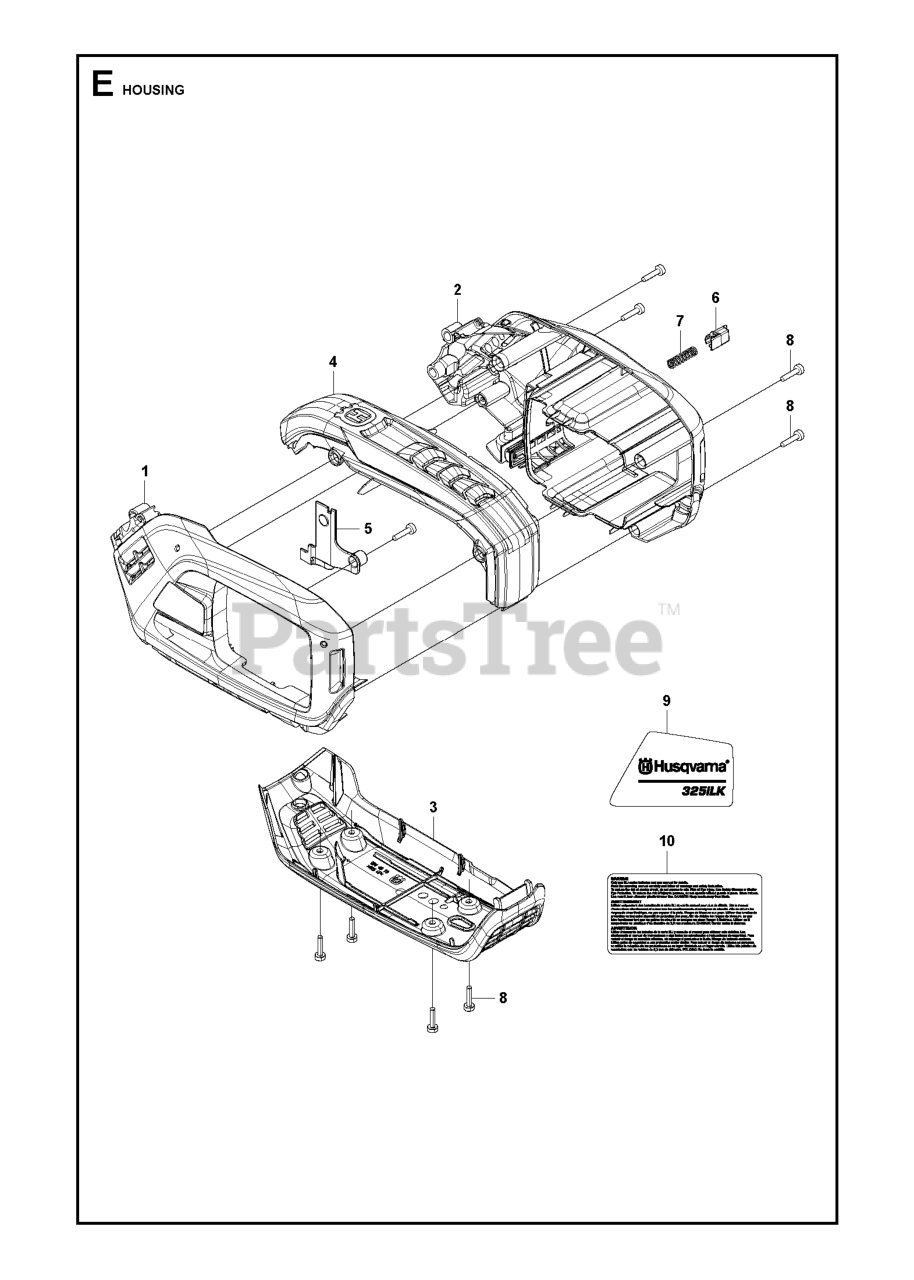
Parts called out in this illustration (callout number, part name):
1	Housings
2	Housings
3	Skid Plates
6	PUSH BUTTON
7	SPRING PUSH OUT
8	SCREW ITXSCT PW4.2X18 10.9 ZN
10	Decals
